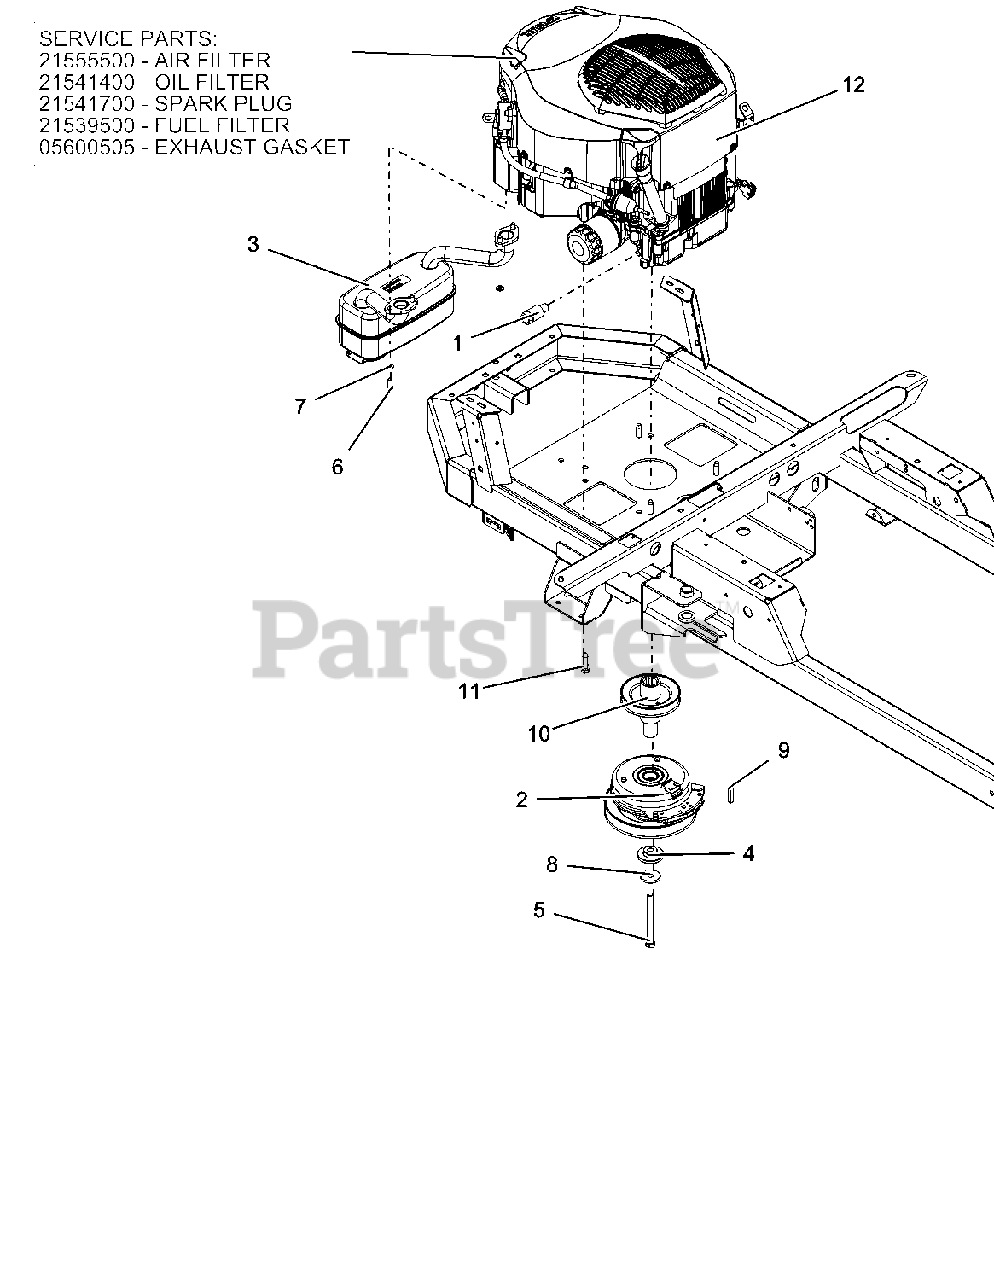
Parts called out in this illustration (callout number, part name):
1	DRAIN, OIL
2	CLUTCH,105FTLB MONOPOLE 6.83"
3	MUFFLER, KOHLER TWIN
4	BSHG-FLG .469X1.06X.574X2.0
5	BLT-HEX.438-20X4.5GR8YZ NYTORQ
6	SCR-CAP .31-18X.75 S/HD
7	@WSHR-LK .31X.078 REG YWZC
8	WASHER, 7/16" SPRING DISK
9	KEY-SQ .25 X 1.25 X .25 SAE
10	WLDMT, DRIVE SHEAVE-X
11	@SCR-TAP .38-16X1.25 HWH TR YZ
12	FILTER, FUEL
12	PLUG, SPARK
12	FILTER, ENGINE OIL (COURAGE)
12	GASKET, MUFFLER COURAGE TWIN
12	AIR CLEANER, KOHLER
12	ENGINE, KOHLER 24HP TWIN
